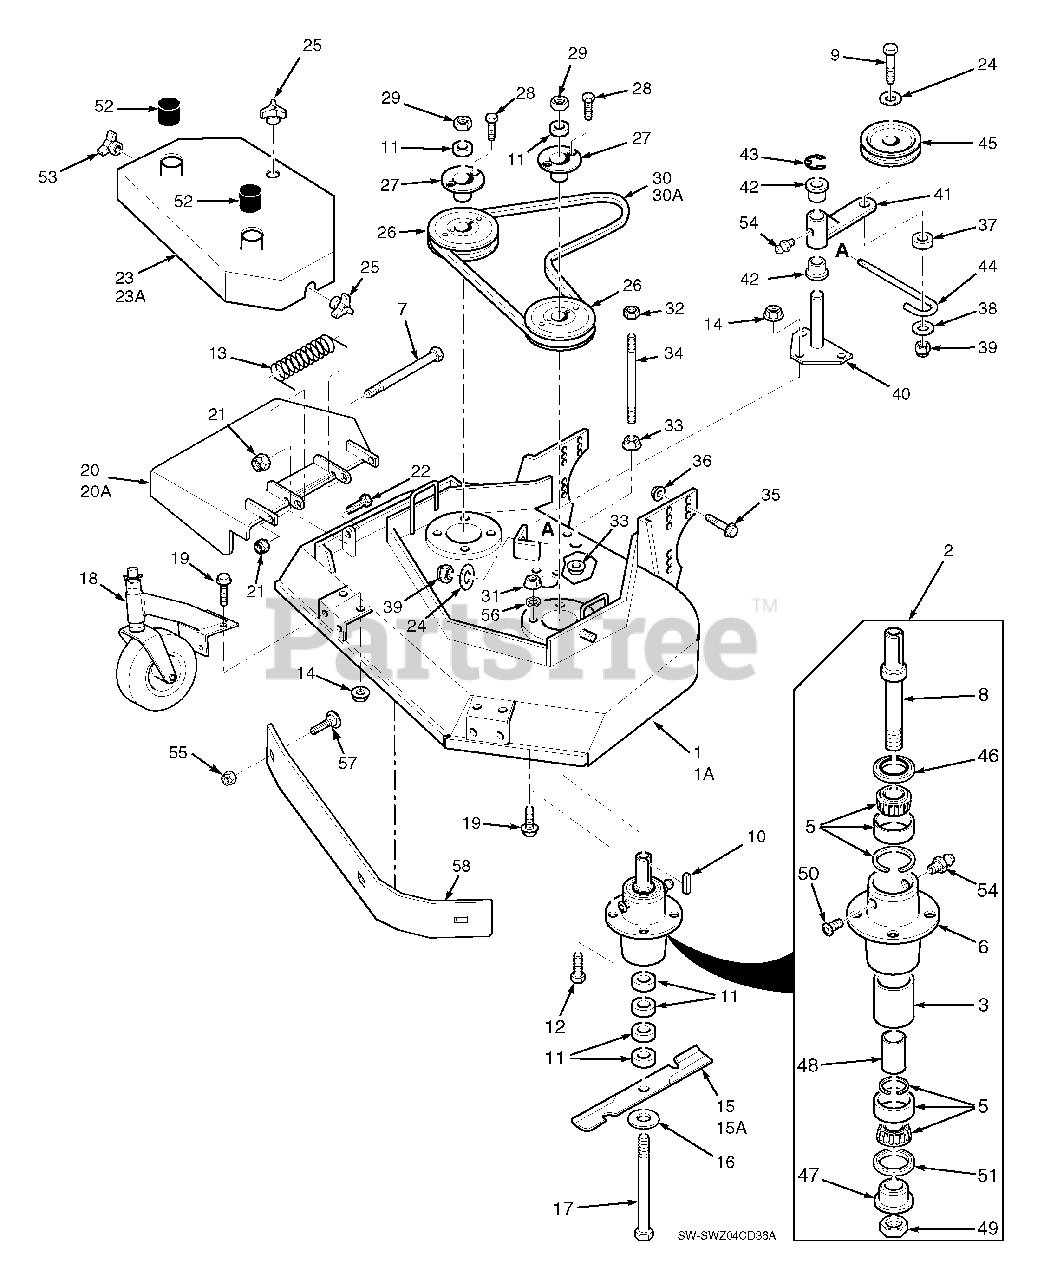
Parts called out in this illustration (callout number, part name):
1	Cutter Deck
1A	Cutter Deck
2	Cutter Spindle Assy.
3	Spacer, Outside
5	Tapered Bearing (Two)
6	Spindle Housing
7	Bolt, 5/16-18 x 4-3/4" Hex Head
8	Spindle Shaft
9	Bolt, 3/8-16 x 3-1/2" Hex Head
10	Key, 1/4 x 1/4 x 2"
11	Spacer, Cutter Blade - Small
12	Bolt, 5/16-18 x 1-1/2" Hex Head Grade 8
13	Spring, Chute Return
14	Nut 5/16-18 Serrated Flange
15	Cutter Blade, 16-1/2" Marbain
15	Cutter Blade, 18" Marbain
15A	Cutter Blade 16-1/2 Hi Lift Marbain
15A	Cutter Blade, 18 Hi Lift Marbain
16	Flatwasher, 5/8 W
17	Hex Hd. Bolt, 5/8-11 x 9-1/2"
18	Caster Assembly
19	Cpscrw,5/16-18 x 3/4" Ser.Flg. Hex Head
20	Discharge Chute
20A	Discharge Chute
21	Hex Nut, 5/16-18 Elastic Stop
22	Hex Hd Bolt, 5/16-18 x 1"
23	Belt Cover Assy
23A	Belt Cover Assy
24	Flat Washer, 3/8" Special
25	Wing Nut, 3/8-16
26	Pulley
27	Tapered Hub
28	Hex Hd. Bolt, 1/4-20 x 1"
29	Hex Nut, 5/8-11
30	Belt, Blade Drive
30A	Belt, Blade Drive
31	Elastic Stop Nut, 5/16-18 Grade 8
32	Hex Nut, 3/8-16 Center Locknut
33	Nut, 3/8-16 Serrated Flange
34	Support, Belt Cover
35	Cpscrw, 1/2-13 x 1"Ser.Flg. HH
36	Nut, 1/2-13 Spiralock
37	Spacer, J-Hook
38	Washer, 3/8 x 1-1/2 x 16 GA
39	Elastic Stop Nut, 3/8-16
40	Idler Pivot
41	Idler Arm Assy.
42	Bronze Bearing
43	Retaining Ring, 1-1/8" Ext. ”E”
44	J-Hook
45	Idler Pulley, Belt Clutch
46	Seal, Cutter Spindle
47	Spindle Bushing
48	Spacer, Inside
49	Nut,1.06-18
50	Relief Fitting, Cutter Spindle
51	Seal, Cutter Spindle
52	Spindle Shield
53	Wing Nut, 3/8-16 (Small) RH side
54	Grease Fitting
55	Nut, Hex Elastic Stop 3/8-16
56	Lock Washer, 5/16"
57	Bolt, Carriage 3/8-16 x 1"
58	Baffle Weldment
